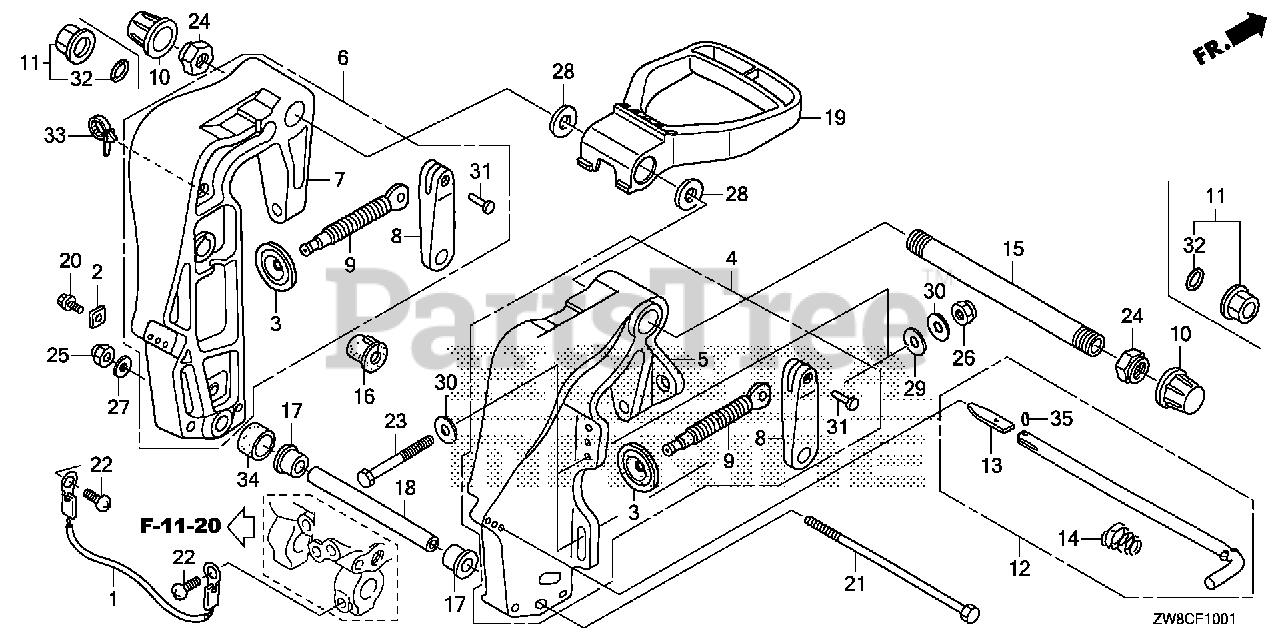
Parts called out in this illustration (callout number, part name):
1	WIRE, LEAD (1.5X170MM)
2	METAL, ANODE
3	PLATE, PUSH
4	BRACKET, R. STERN *NHB14M* (AQUA MARINE SILVER METALLIC)
5	BRACKET, R. STERN *NHB14M* (AQUA MARINE SILVER METALLIC)
6	BRACKET, L. STERN *NHB14M* (AQUA MARINE SILVER METALLIC)
7	BRACKET, L. STERN *NHB14M* (AQUA MARINE SILVER METALLIC)
8	GRIP, CLAMP
9	SCREW, CLAMP
10	CAP, TILTING BOLT
12	ROD, ADJUSTING
13	STOPPER, ROD
14	SPRING, ADJUSTING ROD
15	SHAFT, TILTING
16	BUSH, MOTOR CODE
17	BUSH, CYLINDER (LOWER)
18	COLLAR, CYLINDER (LOWER)
19	HANDLE, CARRYING REMOTE
20	BOLT, FLANGE (6X12) Use from Frame SN 1005249.
21	BOLT, HEX. (8X203)
22	SCREW, PAN (6X8)
24	NUT, SELF-LOCK (7/8-14UNF)
25	NUT, SELF-LOCK (8MM)
27	WASHER, PLAIN (8MM) Use up to Frame SN 4800712.
28	WASHER, WAVE (22MM)
31	RIVET (4X22.6)
33	CLIP, HARNESS BAND (145MM) (BLACK)
34	COLLAR, DISTANCE
35	PIN, SPRING (2.5X8)
